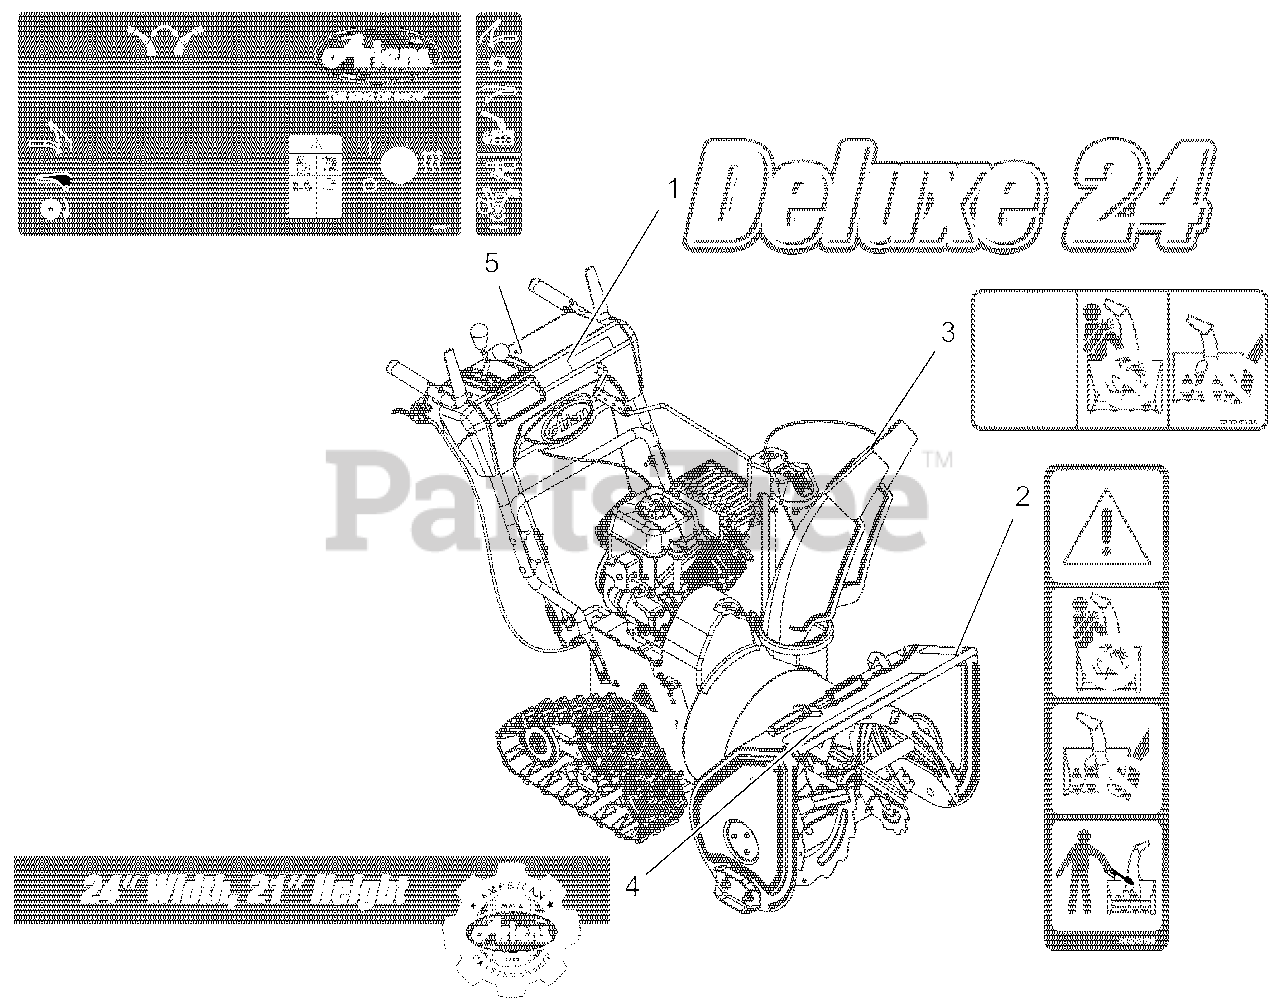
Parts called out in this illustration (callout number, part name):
1	DECAL,ST24 DELUXE-COMPACT DASH
2	DECAL, DANGER - ROTATING PARTS
3	DECAL, DANGER
5	DECAL, CONTROL - DLX TRACK HW
